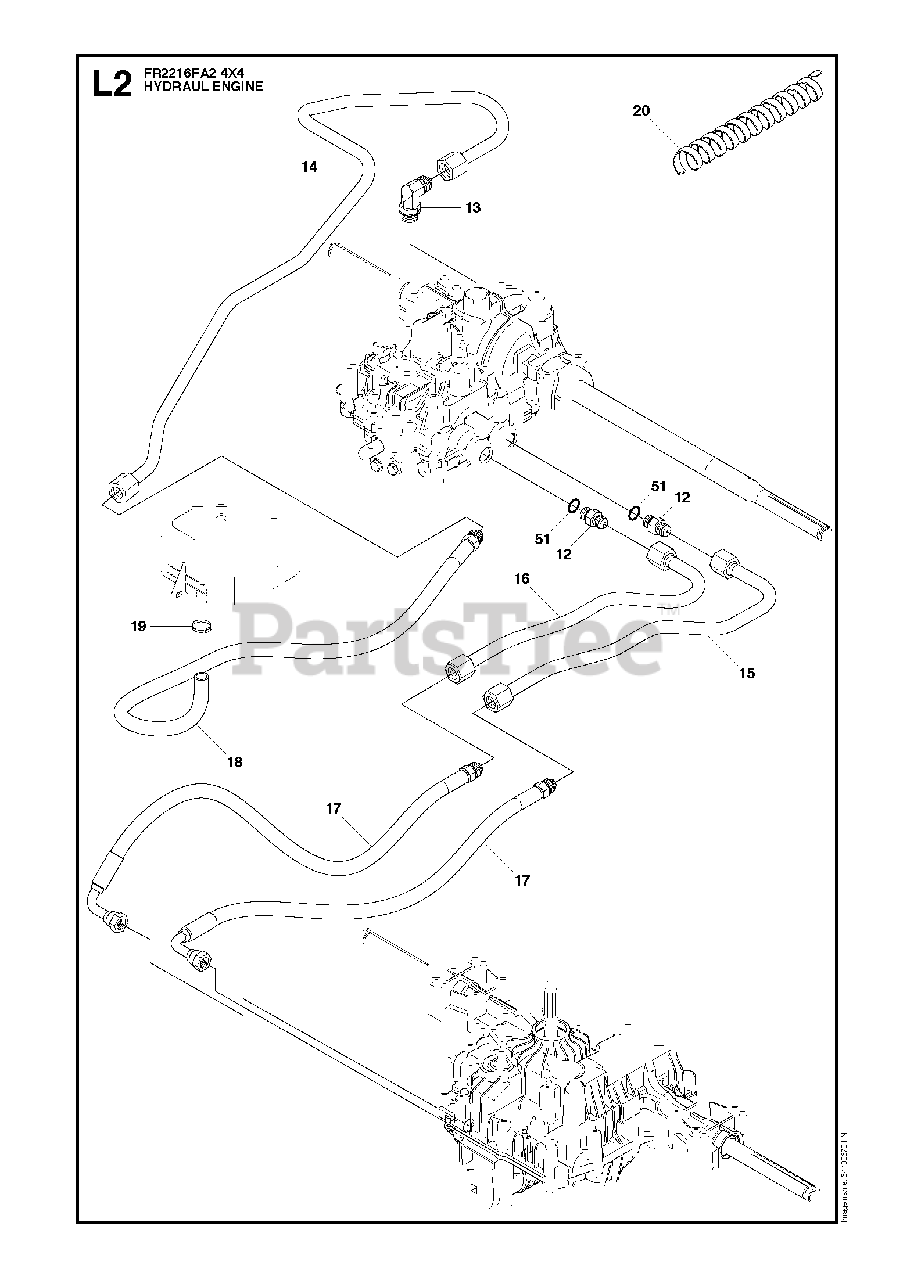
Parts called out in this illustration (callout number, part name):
12	PIPE FITTING
14	HYDRAULIC PIPE
15	HYDRAULIC PIPE
16	HYDRAULIC PIPE
17	HYDRAULIC HOSE
19	HOSE CLIP
20	PROTECTOR
